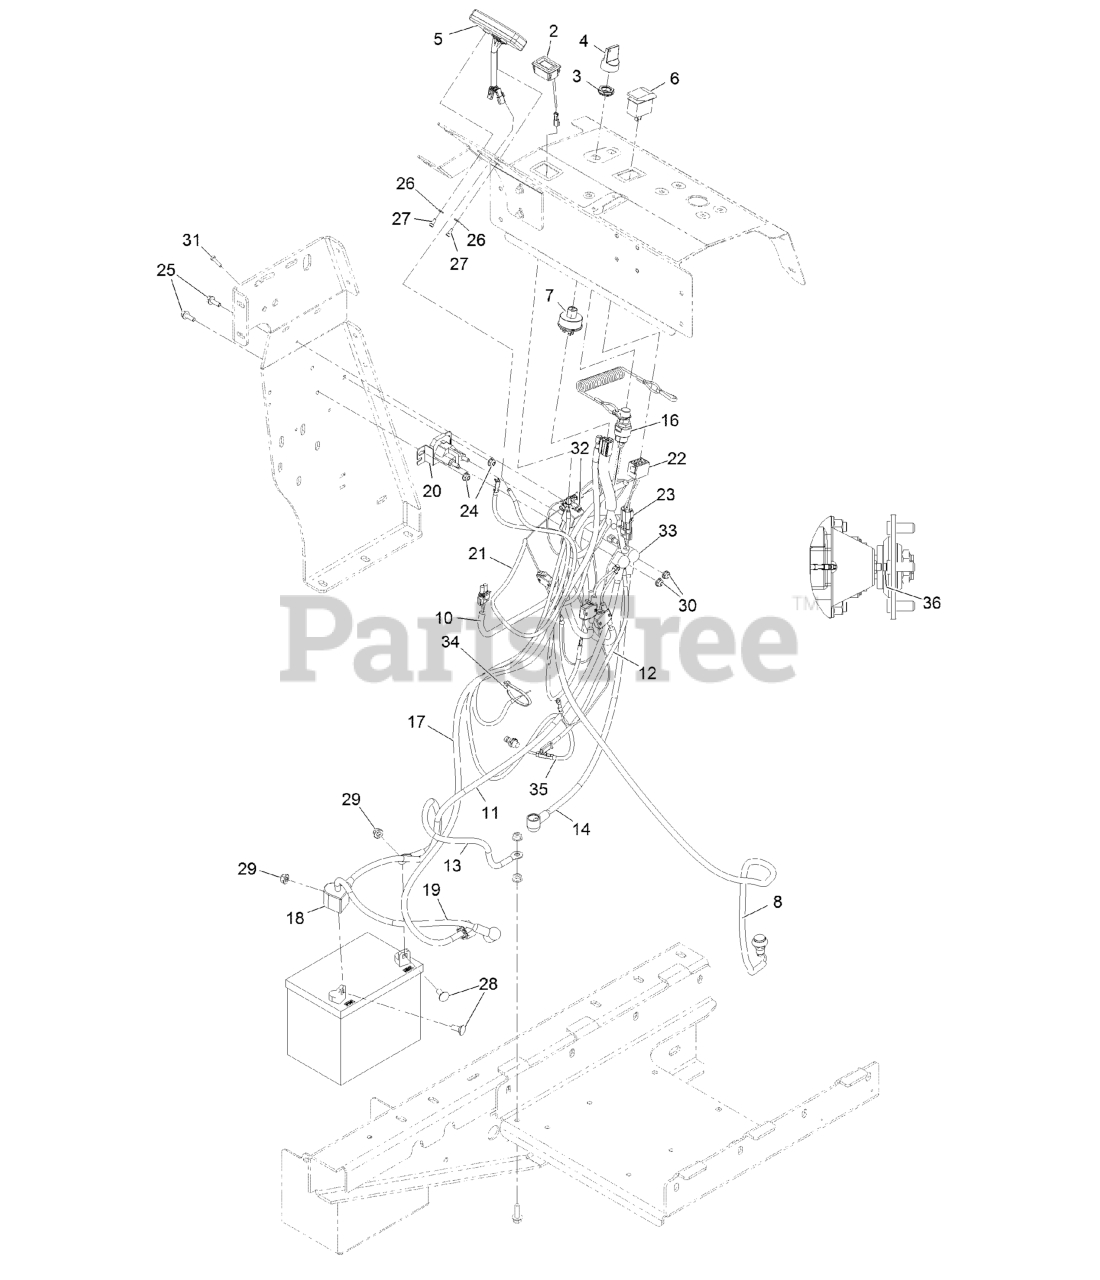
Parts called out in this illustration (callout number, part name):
2	METER-TACH/HOUR
3	NUT-SWITCH, KEY
4	KEY-UMBRELLA
5	HEAD ONLY, STRIKER
6	SWITCH-ROCKER
7	SWITCH-IGNITION
8	Switch-Push Button
10	Harness, Main
11	CABLE-POSITIVE
12	Wire-Solenoid
13	CABLE-GROUND
14	CABLE-POSITIVE
16	SWITCH-OP
17	Harness, Alternator
18	Insulator-Battery
19	CABLE-POSITIVE
20	Solenoid-Starter
21	HARNESS-STRIKER
22	CONNECTOR-CARLING, 8F
23	Connector-Wp,2M
24	Nut-Hex Flange
25	Screw-HHF
26	WASHER-FLAT
27	SCREW-HSH
28	SCREW-CARR
29	Nut-Hex Flange
31	SCREW-HH
32	Nut-Hex Flange
33	INSULATOR-SOLENOID
34	TIE-CABLE
35	Cable-Trail Tech, Sensor
36	MAGNET, SPEEDOMETER
